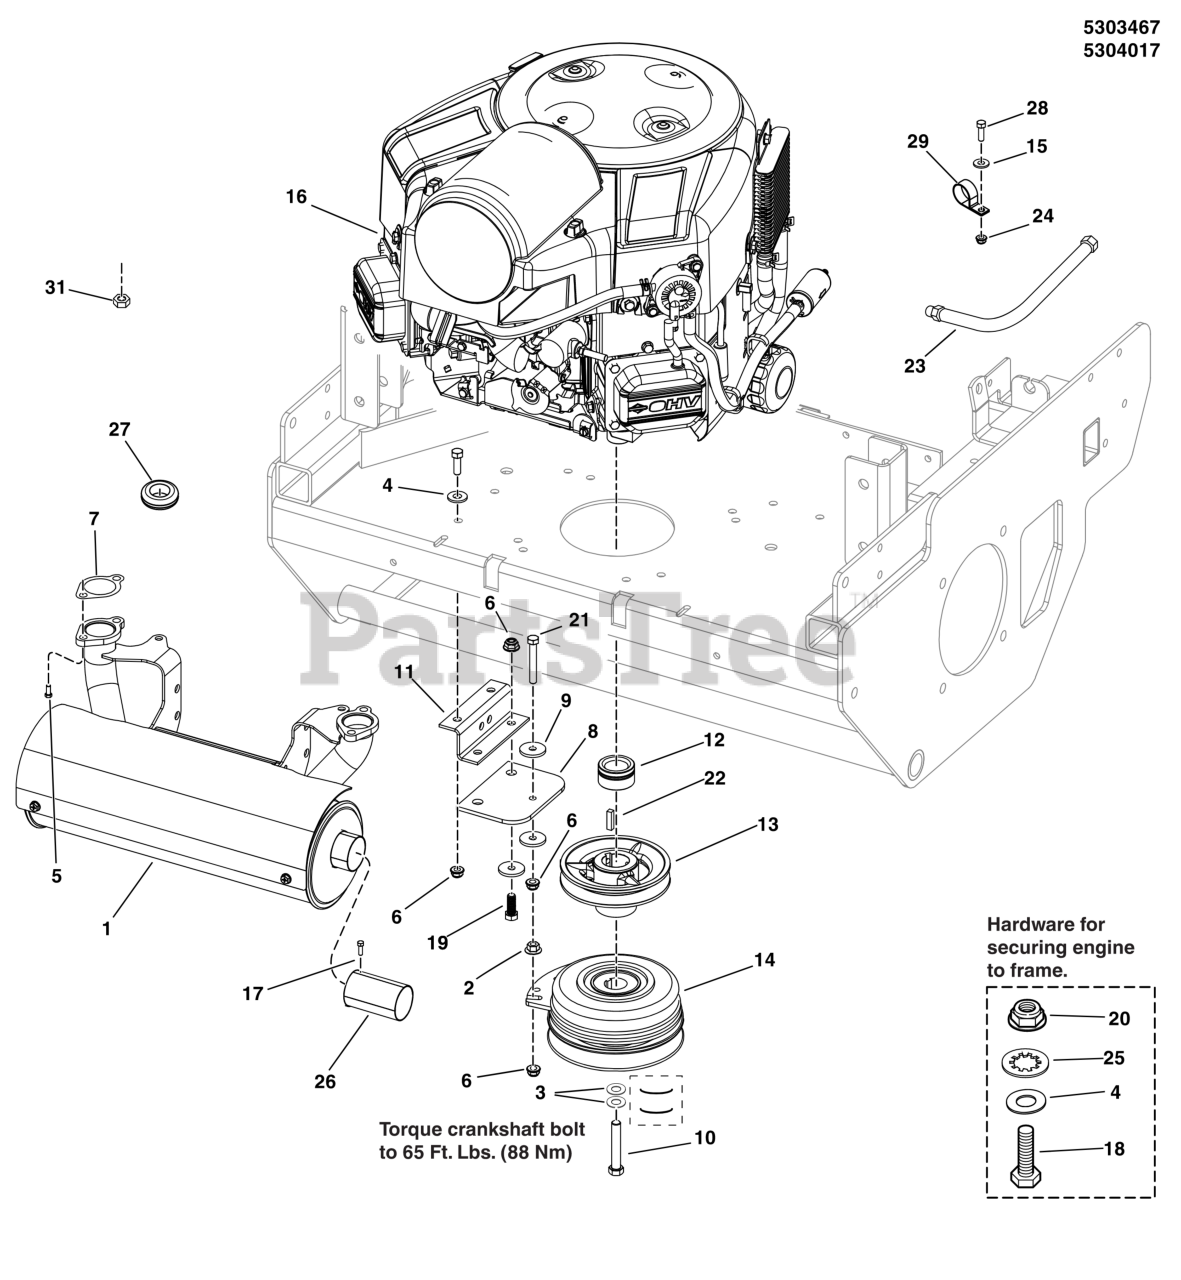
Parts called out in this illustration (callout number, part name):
1	MUFFLER, RIGHT OUTLET ASSY
2	NUT, 5/16-18 HEX SERRATED FLANGE (LARGE)
3	BELLEVILLE WASHER 1.1875 X .442 X .089
4	WASHER, 5/16" SAE
5	SCREW-HEX SEMS LOCK WSHR 5/16-18X0.875
6	NUT, 5/16-18 HEX NYLOCK FLANGE
7	GASKET, EXHAUST
8	CLUTCH ANCHOR PAD
9	WASHER, .34 X 1.25 X 10 GA
10	BOLT, CRANKSHAFT,7/16-20X2-3/4, GD8
11	ANCHOR, CLUTCH - BLK
12	SPACER, 1.13 X 1.75 X 1.35, CZ
13	PULLEY, 4.75 OD X 1-1/8 BORE, BC-48
14	CLUTCH,WARNER,200 'lbs,1.13
15	WASHER, 1/4 SAE
16	ENGINE, 27HP B&S COMM TURF, 1-1/8 X 4.29
16	ENGINE, BRIGGS & STRATTON, VANGUARD
16	ENGINE, BRIGGS & STRATTON, CXi (49T877-0010-G1)
17	SCREW,SELF-TAP,#8-32 X 3/8,WASH HEX, CZ
18	BOLT, 5/16-24 X 1-3/4, GD8, PHOS
19	BOLT, 5/16-18 X 1 GD5 CZ
20	NUT, 5/16-24, TOP LOCK FLANGE, GD8 PHOS
21	BOLT, 5/16-18 X 2-1/4 TFL, GD5 YZ
22	KEY, 1/4 SQ X 1-1/4
23	HOSE, OIL DRAIN
24	NUT, 1/4-20 HEX SERR. FLANGE
25	WASHER, 5/16 INT. TOOTH LOCK
26	EXTENSION, TAILPIPE, 3", BLACK
27	GROMMET, 7/8"ID, 1/4" THICK STK
28	HHCS, 1/4-20 X 0.625, GR5, ZINC/CLEAR
29	CLAMP, VINYL INSULATED, 1.00
31	NUT, 5/16-24 JAM
